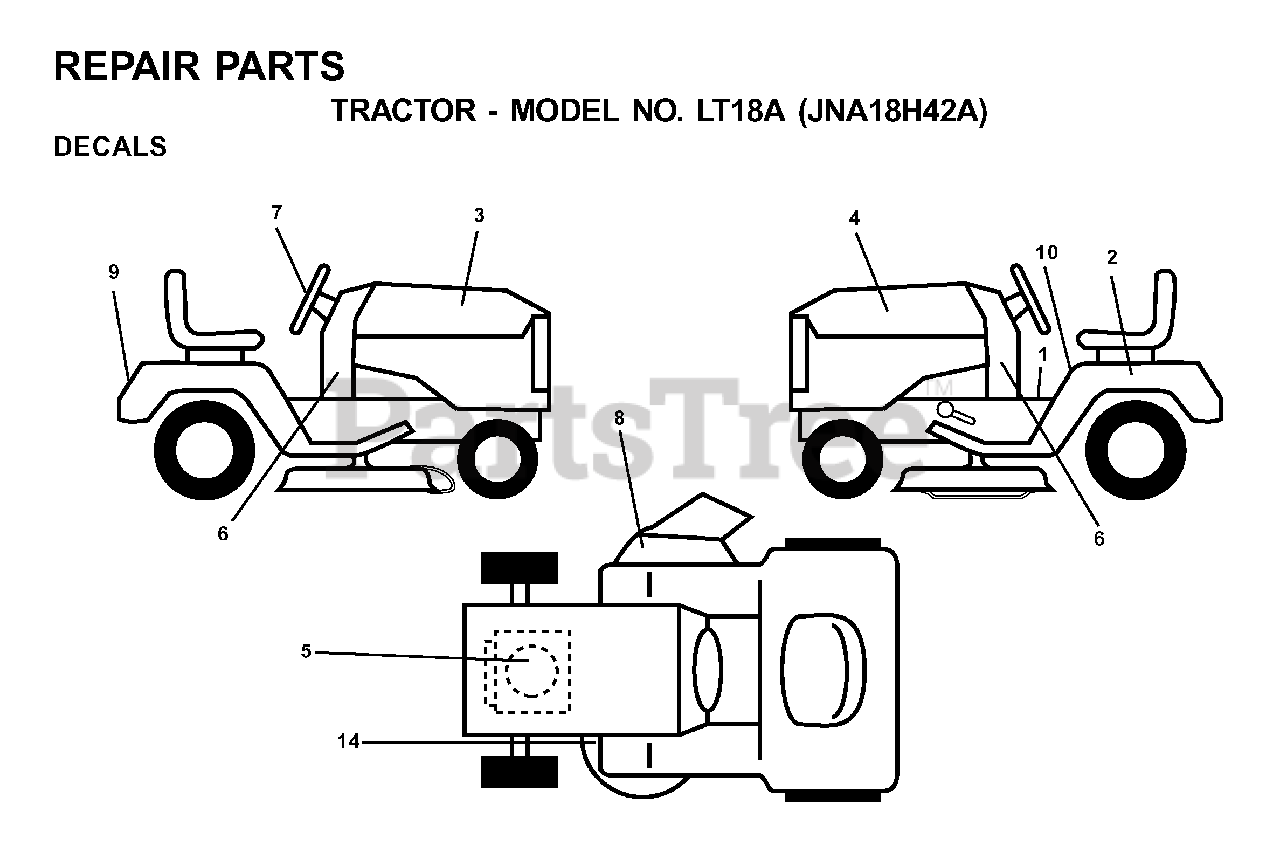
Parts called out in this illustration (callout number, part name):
1	DECAL SET
2	DECAL BTRY SYMBOLS
8	DECAL.WARN.KEEP.HAND.AWAY
10	DECAL FENDER DANGER
14	DECAL V BELT SCHEMATIC
